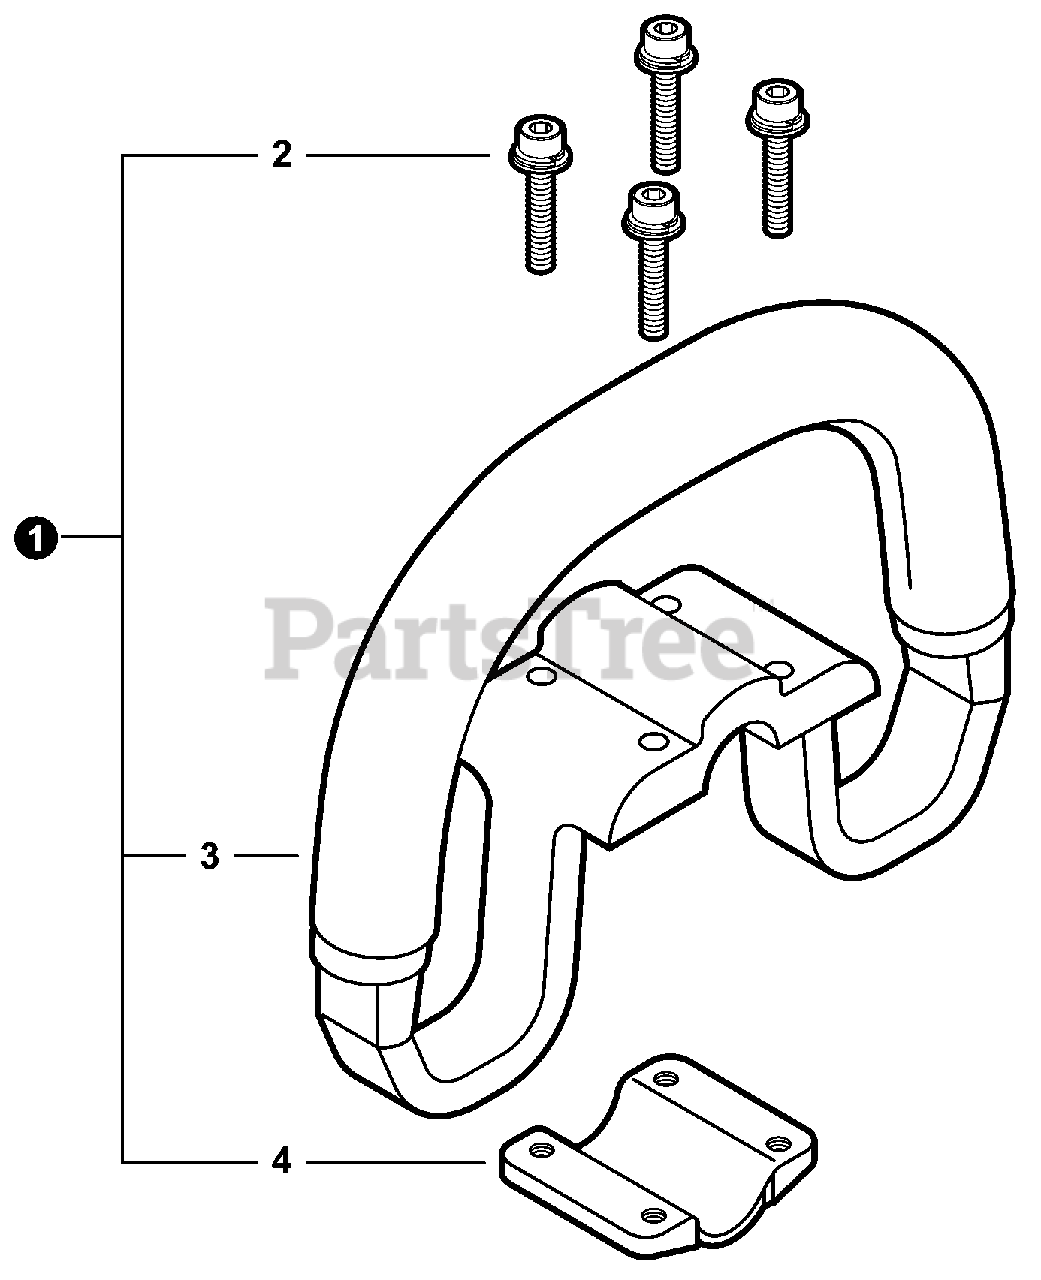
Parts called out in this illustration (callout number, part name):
1	HANDLE ASSY - SUPPORT
2	BOLT M5x25
4	BRACKET, MOUNTING
